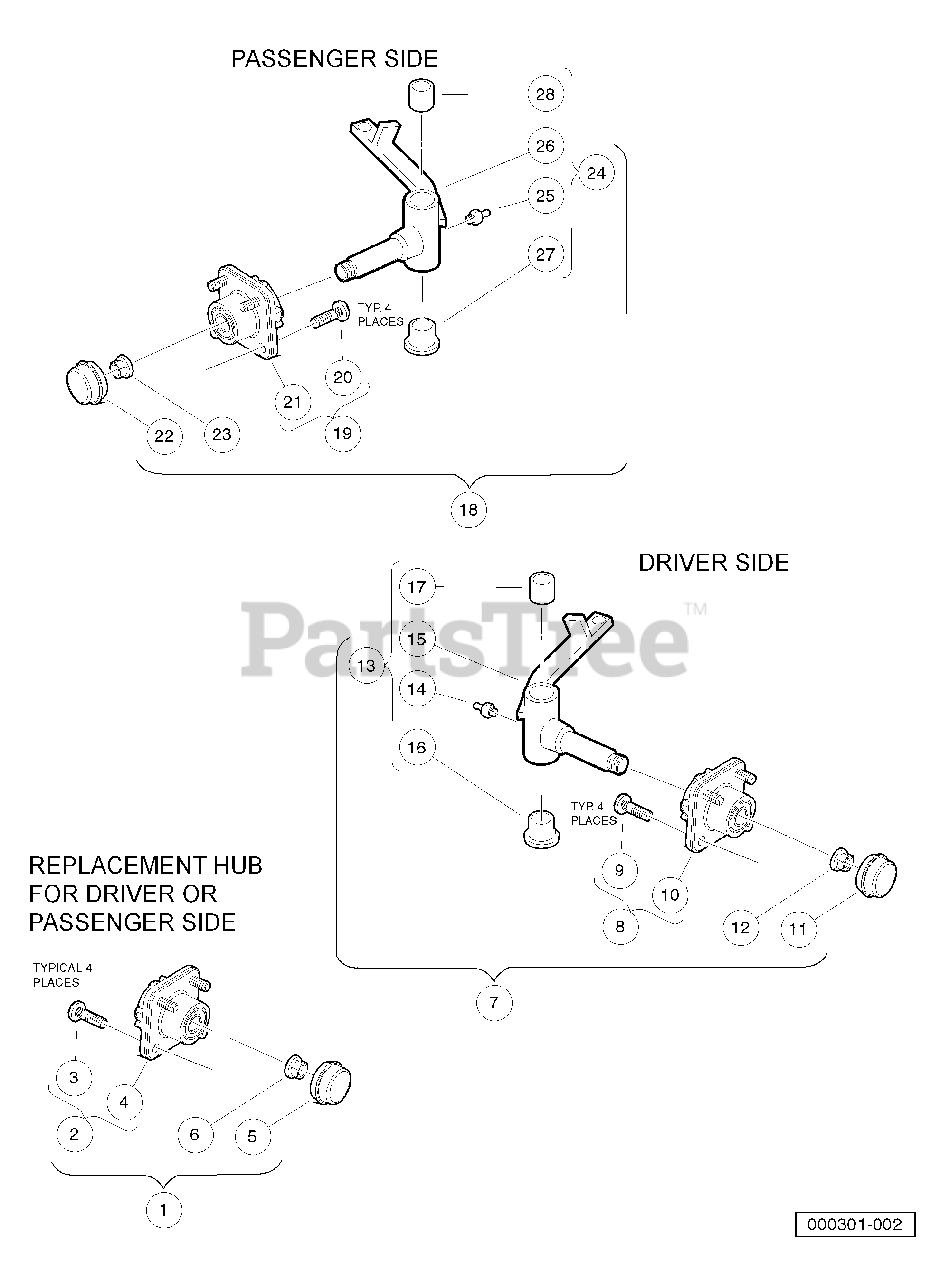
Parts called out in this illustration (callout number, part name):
1	Replacement Kit, Front Hub
2	Front Hub Assembly, Ball Bearing
3	Lug Stud, 1/2-20 UNF, 4037 Stl
4	Hub, Front
5	Cap, Front Hub
6	Hex Nut, Locking Flange, M14x2
7	Asm, Hub And Spindle, Left-Hand Ext
8	Front Hub Assembly, Ball Bearing
9	Lug Stud, 1/2-20 UNF, 4037 Stl
10	Hub, Front
11	Cap, Front Hub
12	Hex Nut, Locking Flange, M14x2
13	Asm, Spindle, LH, Ext
14	Fitting, 1/4-28 Thread-Forming Grease
15	Subasm, Spindle, LH, Ext
16	Bushing, Flanged Bronze
17	Bushing, Bronze Spindle
18	Asm, Hub And Spindle, Right-Hand Ext
19	Front Hub Assembly, Ball Bearing
20	Lug Stud, 1/2-20 UNF, 4037 Stl
21	Hub, Front
22	Cap, Front Hub
23	Hex Nut, Locking Flange, M14x2
24	Asm, Spindle, RH, Ext
25	Fitting, 1/4-28 Thread-Forming Grease
26	Subasm, Spindle, RH, Ext
27	Bushing, Flanged Bronze
28	Bushing, Bronze Spindle
